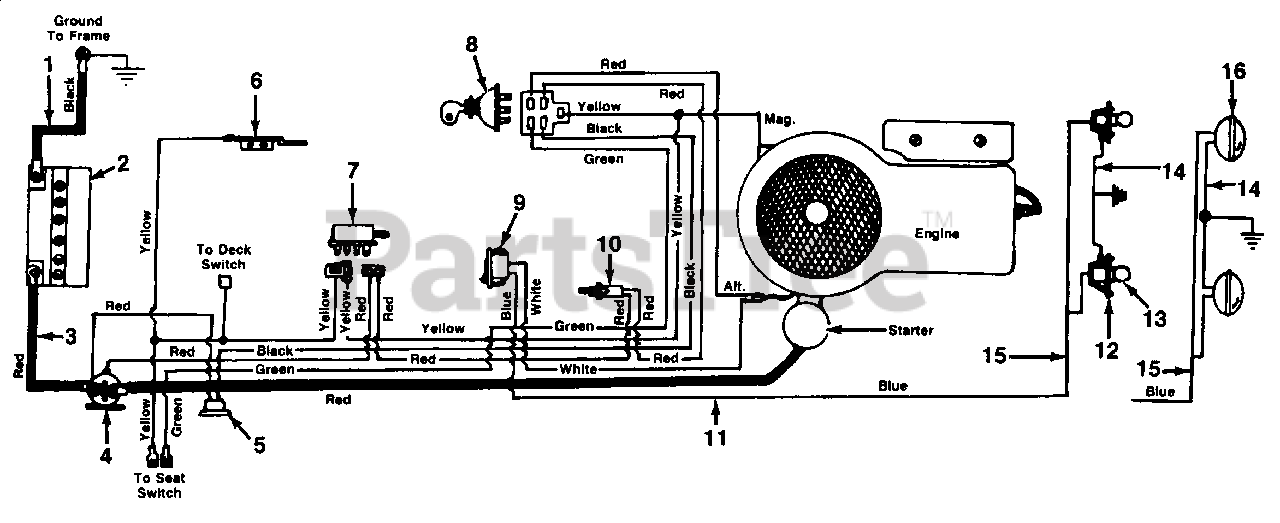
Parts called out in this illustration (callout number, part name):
1	Ground Wire
2	Battery
3	Electric Wire
4	Solenoid
5	Circuit Breaker
6	Spring Switch
7	Safety Switch
8	Key Switch
9	Light Switch
10	Safety Switch (Black)
11	Harness
12	Socket
13	Lamp
14	Ground Wire
15	Headlight Harness
16	Lamp
